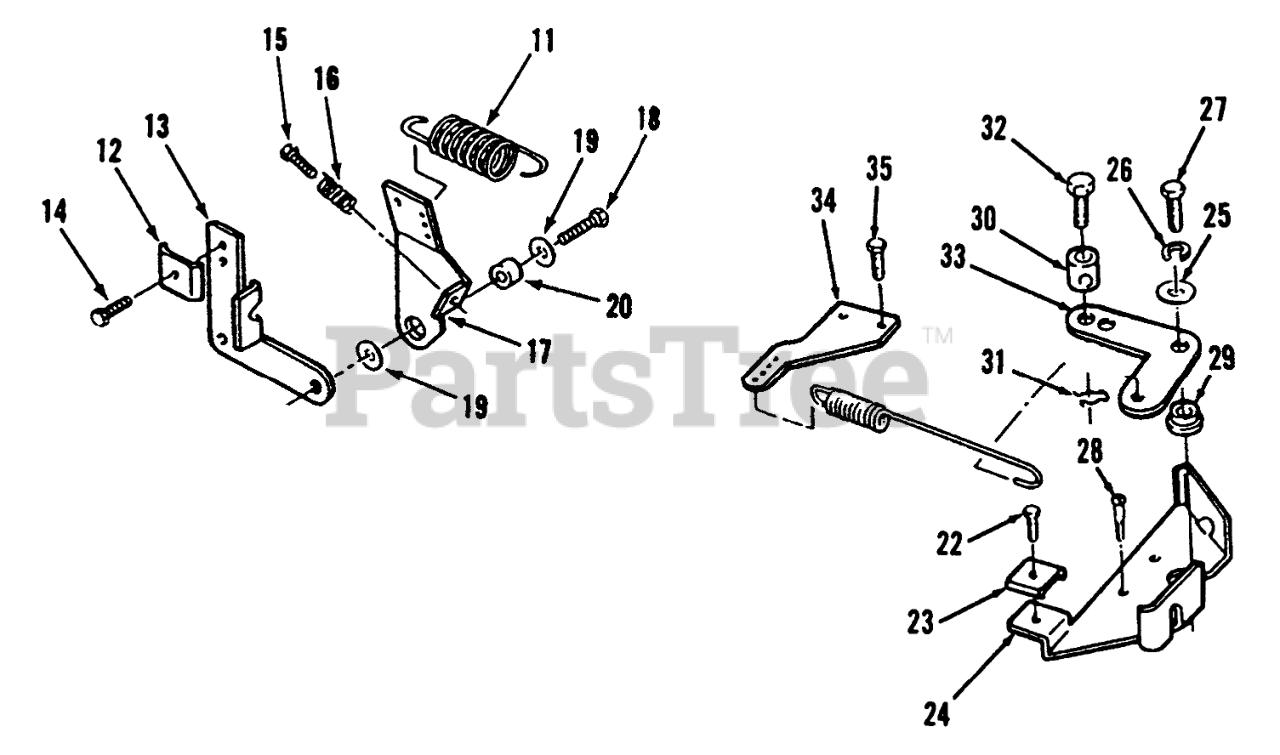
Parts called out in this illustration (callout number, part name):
11	Spring
13	BRACKET
14	Bolt
15	SCREW-TAP
16	Spring
17	GOVERNOR CONTROL ARM
18	SCREW-HWH
19	Screw
20	Bushing
22	TAPPING HEX HD CS
24	BRKT-GOVERNOR CONTRL
25	WASHER-FLAT
26	WASHER-LOCK, SPRING
27	SCREW - CAP HEX HEAD
28	HEX HD CAP SCREW
29	BUSHING-GOV CONTROL
30	Oil Seal
31	PIN-COTTER
32	Bolt
33	LINK-GOV CONTROL
34	ADAPTER-GOV ARM
35	SCREW-TAPPING PAN HD
